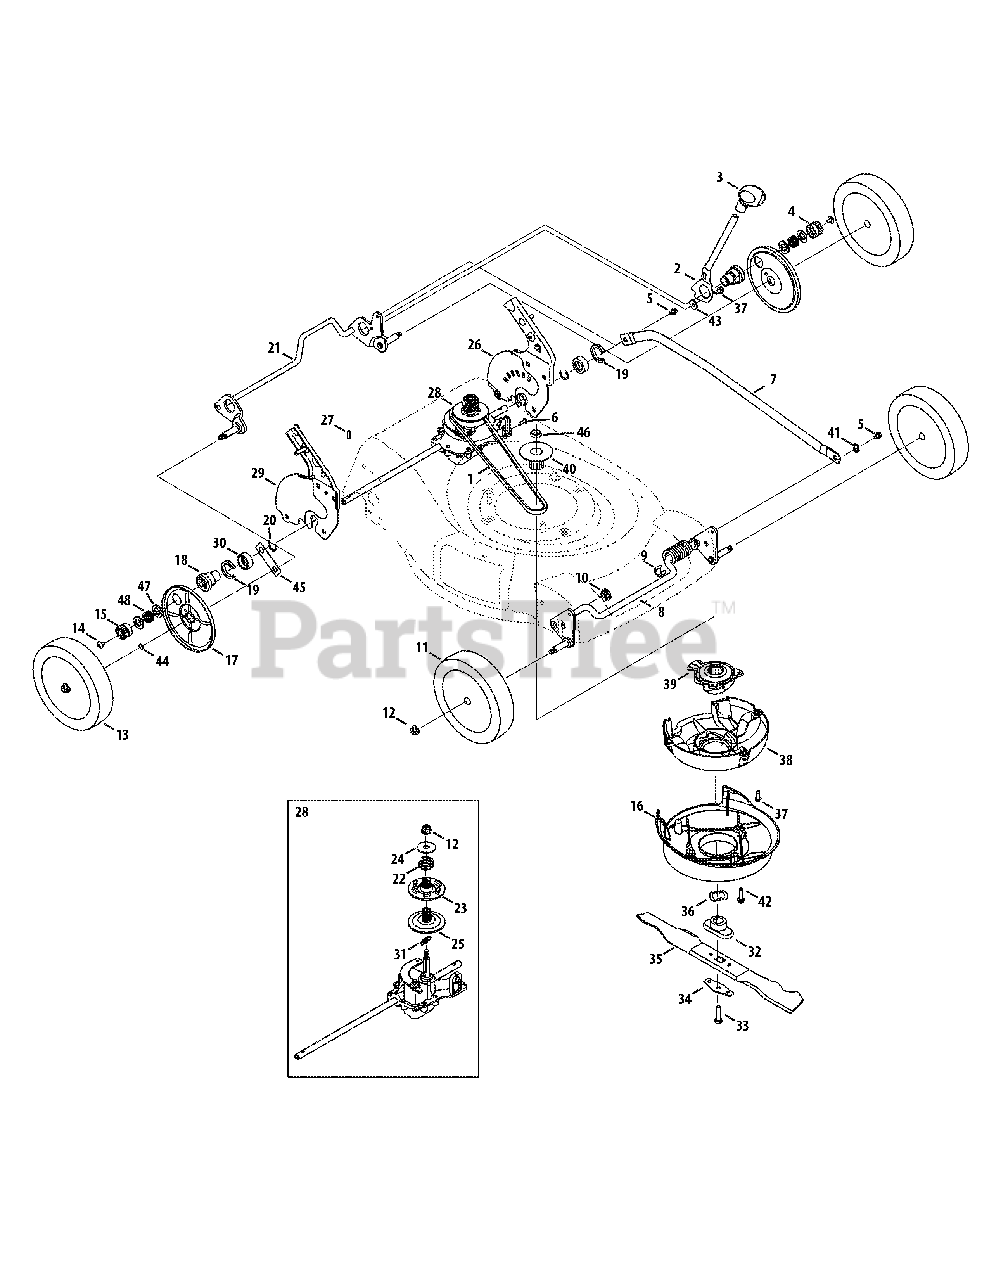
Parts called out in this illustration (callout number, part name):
2	Spring Lever
3	Height Adjuster Knob
4	Spur Gear, 14T - LH
5	Shldr. Screw, 1/4-20 x 0.50
6	Screw, HL 1/4-15 X .750
8	Front Bracket Assembly
9	Clip Spacer
10	Split Hex Flange Bearing
11	Front Wheel
12	Flange Lock Nut, 3/8-16
13	Rear Wheel
14	Screw, 1/4-20 x .39
15	Spur Gear, 14T - RH
17	Wheel Dust Cover
18	Transmission Bearing Support
19	Clip Spacer
20	Retaining Ring .875
21	Rear Bracket Assembly
22	Compression Spring
23	Upper Pulley
24	Flat Washer, .442 x 1.38 x .060
25	Lower Pulley
26	Handle Bracket Assembly LH
27	Dowel Pin
28	Transmission Assembly
29	Handle Bracket Assembly RH
30	Bearing Support Spacer
31	Extension Spring
32	Blade Adapter
33	Screw, 3/8-24 x 1.50
34	Blade Bell Support
35	21" Mulching Blade
36	Washer, Wave, 1.5 x 1.0 x .029
37	TT Screw, 1/4-20 x .500
38	Engine Baffle
39	Lower Pulley Assembly
40	Pulley, Half
41	Washer, Wave, .385 ID x .598 OD
42	Screw, 1/4-15 x 1.250
43	Washer, Bell, .340 x .872 x .080
44	Ring, .375ID x .054
45	Gear Retainer Strap
46	Spcr., 25mm x 1.375
47	Washer, Flat, .508 x 1.00 x .020
48	Spring, Wave
